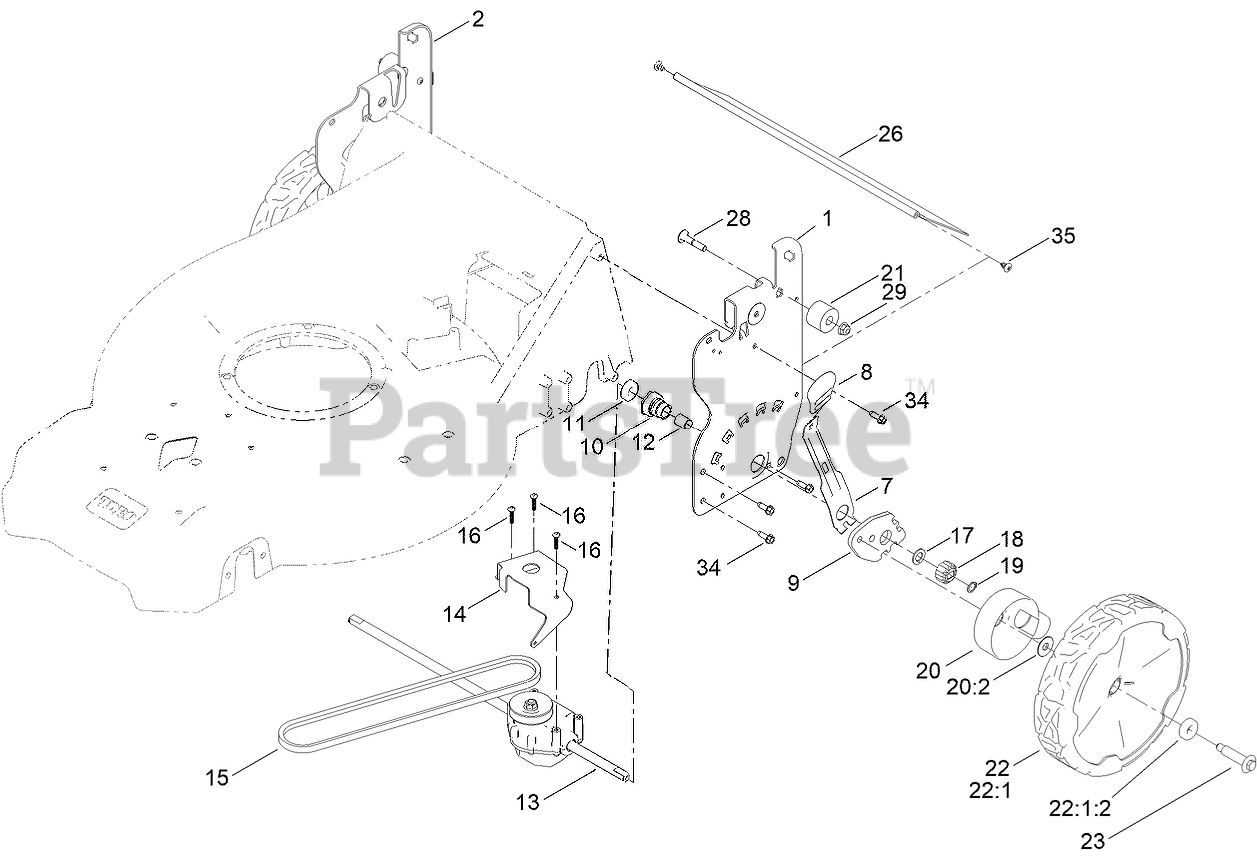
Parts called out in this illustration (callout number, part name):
1	PLATE-HOC, LH (NON-SS)
2	PLATE-HOC, RH (NON-SS)
7	ARM-SPRING
8	KNOB-HOC
9	ARM-PIVOT, REAR
10	RETAINER-BUSHING, HOC
11	BEARING-WHEEL
12	BUSHING-SLEEVE
13	TRANSMISSION-RWD, 5.25:1
14	BRACKET-TRANS, RWD HI
15	BELT-V
16	SCREW-PLASTITE
17	WASHER-THRUST
18	GEAR-PINION, 15T
19	RING-RETAINING
20	ASM-COVER, GEAR
20:2	WASHER-STEPPED
21	BUMPER-ISOLATOR
22	ASM-9.65" WHEEL, GEARED
22:1	ASM-WHEEL, 9.65" (BEARINGS)
22:1:2	BEARING-WHEEL
23	WHEEL BOLT
26	SHIELD-TRAILING
28	SCREW-HH
29	NUT-HF
34	SCREW-HWHTF
35	SCREW-PTH
